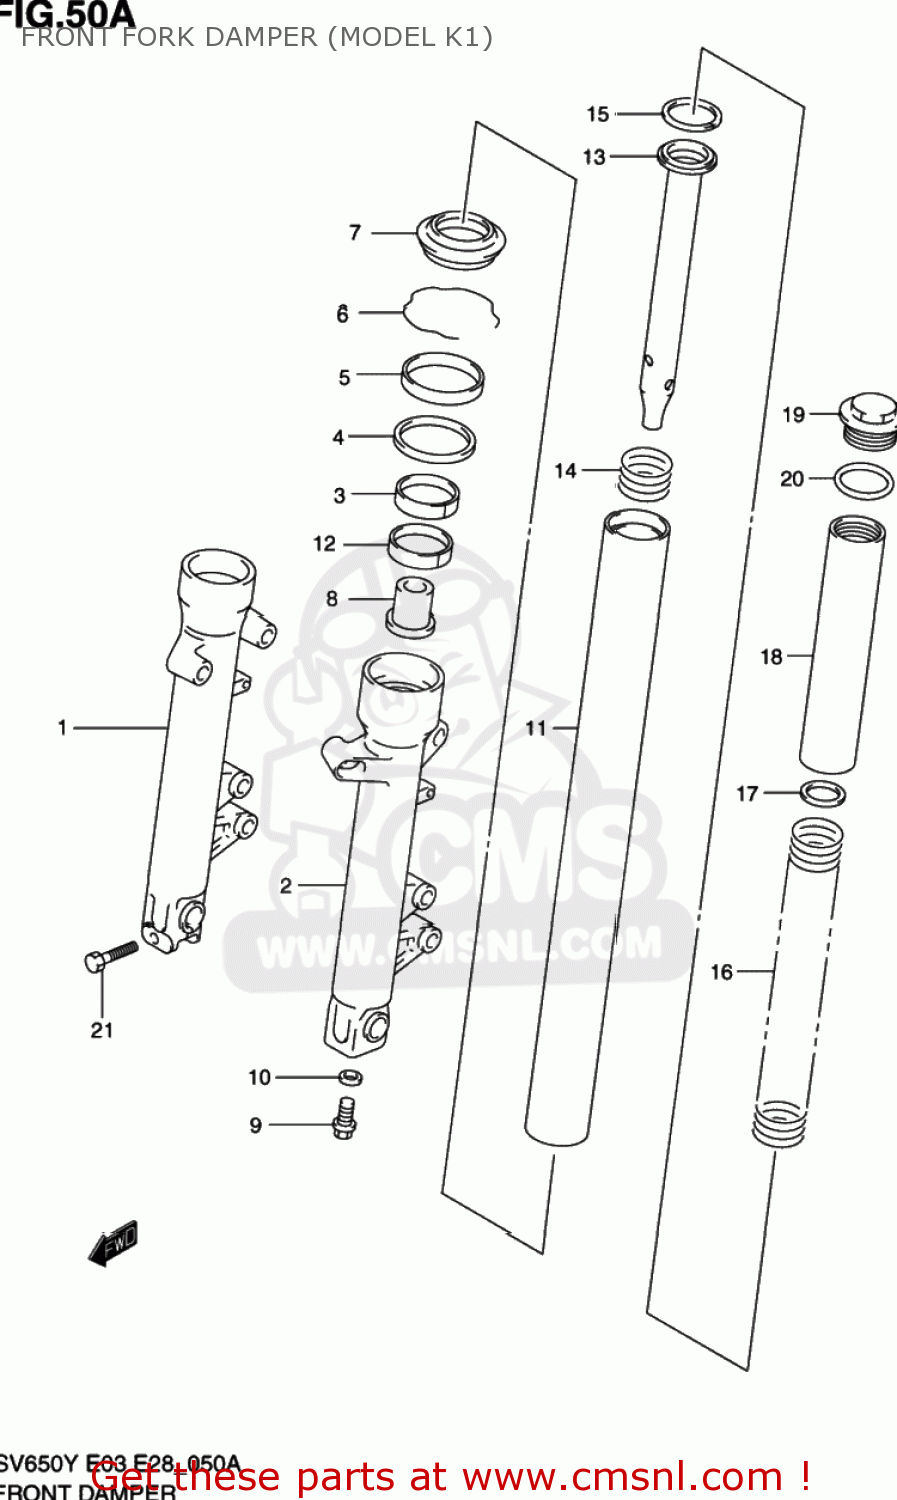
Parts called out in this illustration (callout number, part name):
1	TUBE,OUTER,R
2	TUBE,OUTER,LEFT
3	METAL,SLIDE
4	WASHER,FORK OIL SEAL
5	SEAL,OIL
6	RING,OIL SEAL STOPPER
7	SEAL,DUST
8	PIECE,OIL LOCK
9	BOLT,FORK CYLINDER(10X25)
10	GASKET (NAS)
11	TUBE,INNER
12	PISTON
13	CYLINDER
14	SPRING,REBOUND
15	RING,PISTON
16	SPRING
17	WASHER(22.5X35.9X1.6)
18	SPACER,SPRING
19	CAP,FORK
20	O RING(D:3.5,ID:31.7)
21	BOLT
